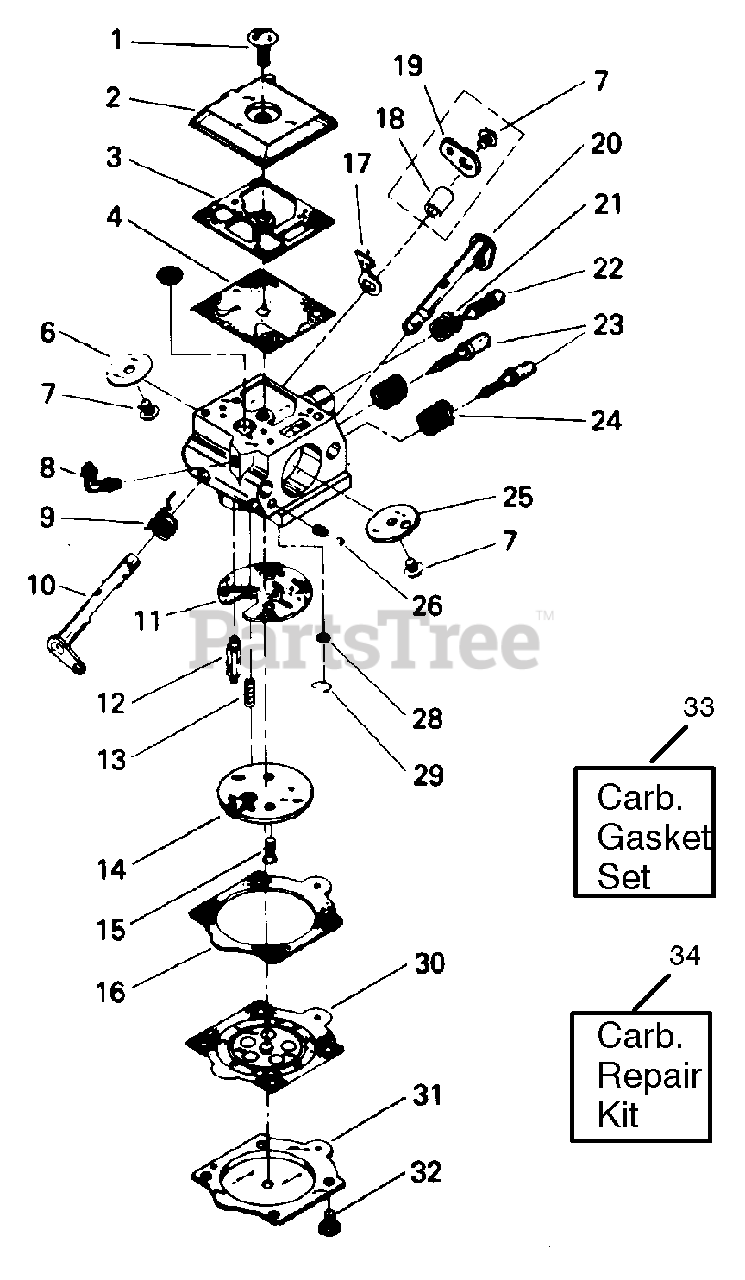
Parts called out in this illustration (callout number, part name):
1	Pump Cover Screw
2	Fuel Pump Cover
3	Fuel Pump Gasket
4	Fuel Diaphragm
6	Throttle Valve
7	Valve Screw
8	Fitting-Inlet(Elbow)
9	Throttle Ret. Spring
10	Throttle Shaft Ass'y.
11	Circuit Gasket
12	Inlet Needle Valve
13	Metering Lever Spring
14	Circuit Plate Ass'y.
15	Circuit Plate Ass'y.
16	Mtrg. Diaphragm Gasket
17	Throttle Stop
18	Throttle Lever Bushing
19	Throttle Lever (Outer)
20	Choke Shaft Ass'y.
21	Idle Screw Spring
22	Idle Adj. Screw
23	Hi & Lo Needle
24	Spring-Needle Fuel Mix
25	Choke Valve
26	Choke Friction Ball
28	Check Valve Screen
29	Screen Retaining Ring
30	Diaph. Mtrg. Ass'y.
31	Mtrg. Diaphragm Cover
32	Mtrg. Cover Screw Ass'y.
33	Carb. Gasket Kit
34	Carb. Kwik Repair Kit
